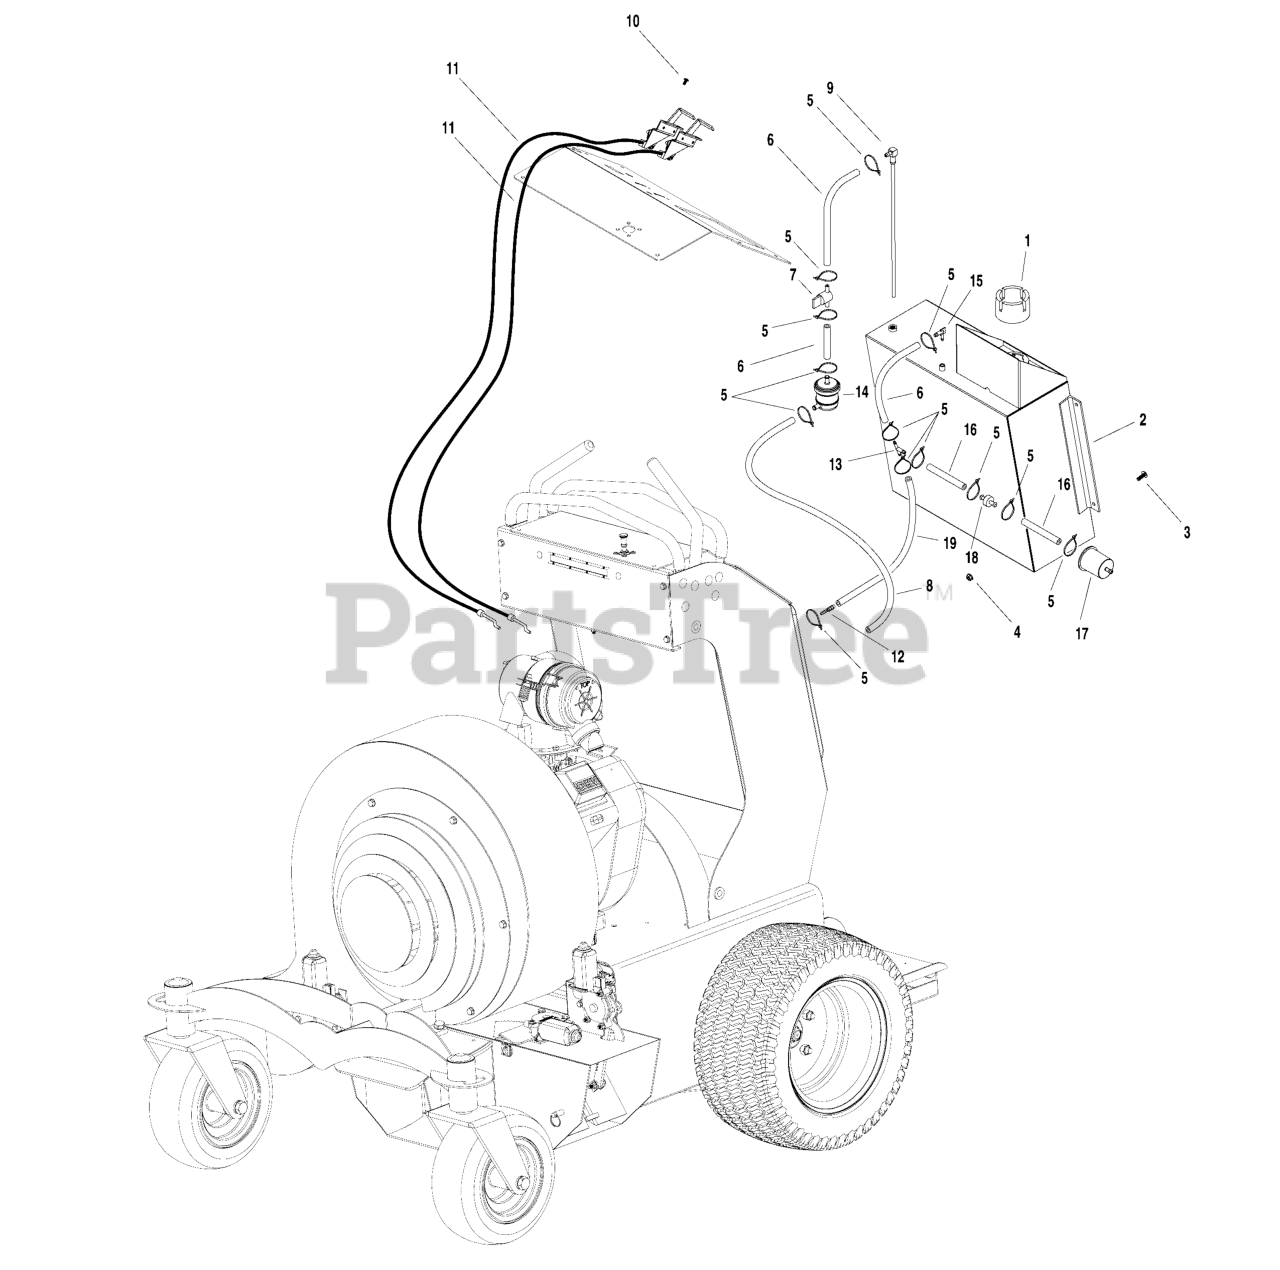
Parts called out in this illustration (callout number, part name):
1	FUEL CAP, 2.0, NON VENTED
2	WELD, FUEL TANK, BLOWER
2	ASSM, FUEL TANK, BLOWER
3	SCREW, 1/4-20 X 3/4, FPHMS, SS
4	NUT, 1/4-20 HEX SERR. FLANGE
5	TIE, SELF-LOCKING, 6"
6	HOSE, 1/4" FUEL, 6" LONG
7	VALVE, FUEL SHUT OFF
8	1/4" Fuel Line, 5" Long
9	PICKUP TUBE ASM,FUEL 16.75
10	SCREW, #10-16 X 1/2, SLF DRLNG, CZ
11	CABLE, THROTTLE/CHOKE
12	FITTING, 1/4X3/16 REDUCER
13	FITTING, 1/4 TEE,BARB TYPE
14	FUEL FILTER (110-17-5403)
15	FITTING, 90, 1/4-18 NPT NYLON
16	HOSE, 1/4" FUEL, 2.50"
17	EMISSION FILTER (110-17-5404)
18	CHECK VALVE ASMY
19	1/4" Fuel Line, 4" Long
